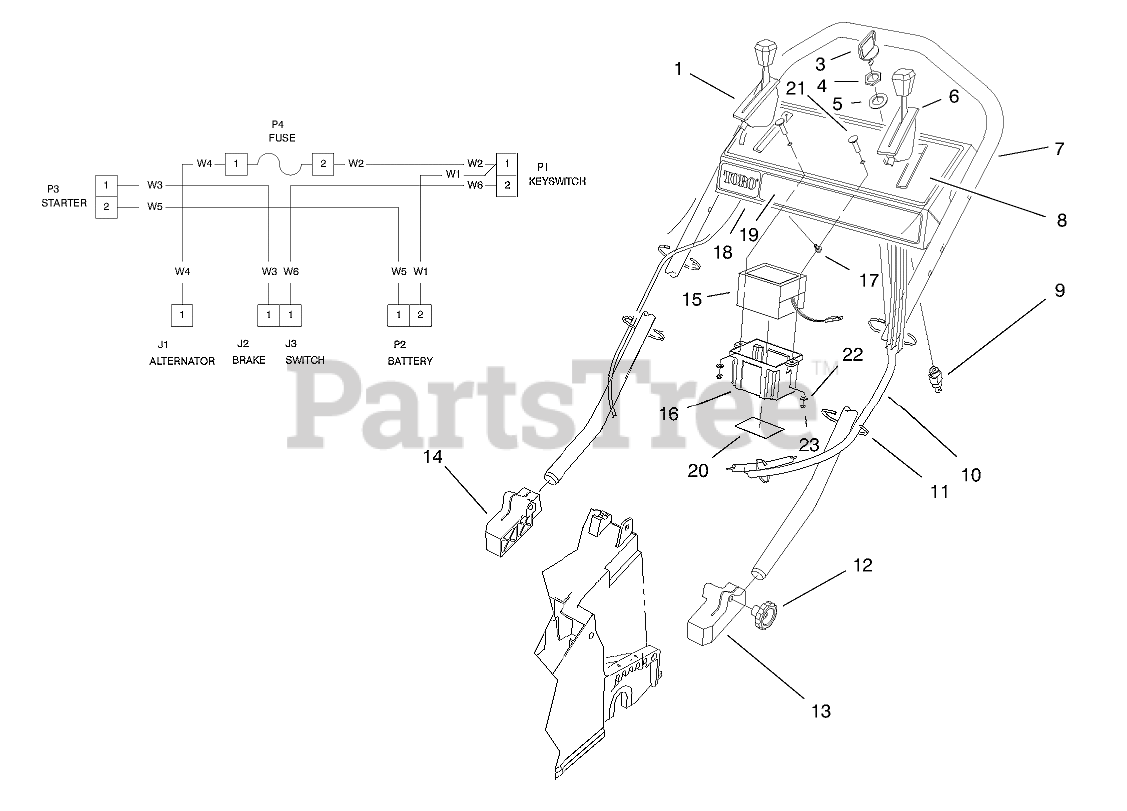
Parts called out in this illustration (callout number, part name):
1	CONTROL-SPEED, GROUND
3	KEY-IGNITION
4	NUT-HH
5	WASHER-TOOTH, INTERNAL
6	CONTROL - THROTTLE
7	HANDLE
8	DECAL - INSTRUCTION
9	Switch-Starter (Incl. Ref. #4 & 5)
10	WIRE HARNESS
11	TIE-CABLE
13	MOUNT-HANDLE, LH
14	MOUNT-HANDLE, RH
15	BATTERY ASSEMBLY
16	COVER - BATTERY
17	SCREW-TAP
18	Panel-Control (Incl. Ref. #8 & 19)
19	DECAL - PANEL KEY
20	DECAL-BATTERY
21	SCREW-CARR
22	WASHER-FLAT
23	NUT-LOCK, NI
